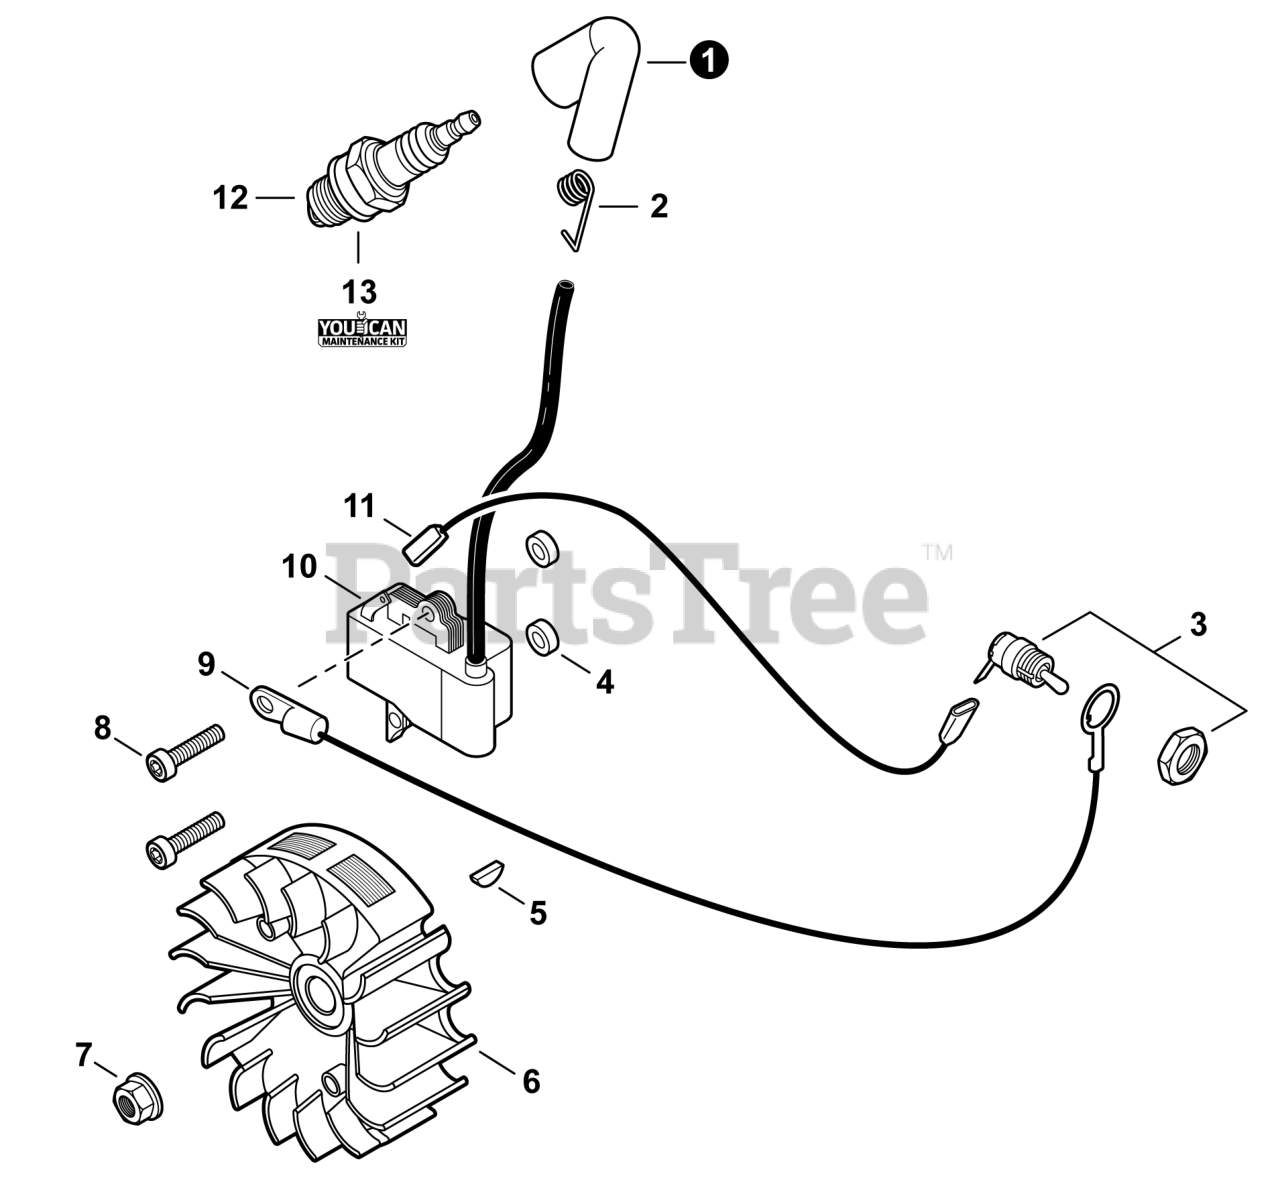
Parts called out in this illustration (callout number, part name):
1	CAP, SPARK PLUG
2	TERMINAL, SPARK PLUG
3	SWITCH, ON-OFF
4	WASHER 5.2x12x3
5	KEY, WOODRUFF
6	FLYWHEEL
7	NUT, FLANGE M8
8	BOLT, TORX 5x20
9	LEAD - GROUND L= 255
10	COIL, IGNITION
11	LEAD - IGNITION
12	SPARK PLUG - BPMR8Y
13	TUNE-UP KIT - YOUCANT
